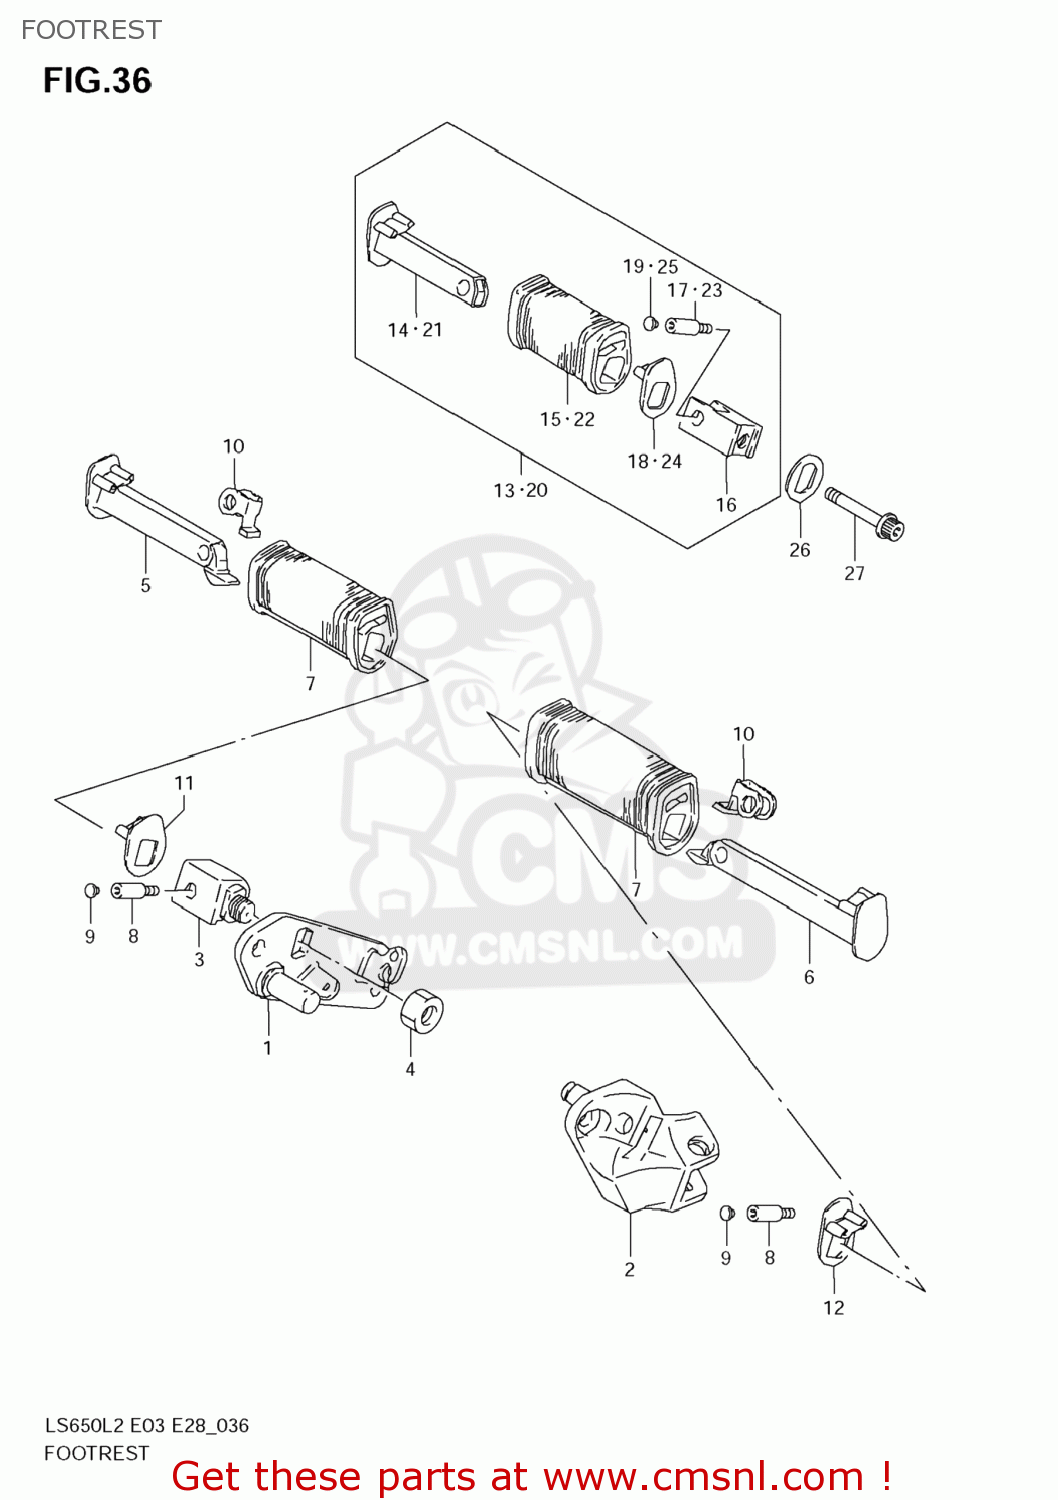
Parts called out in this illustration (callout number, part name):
1	BRACKET,FR FOOTREST,R
2	BRACKET,FR FOOTREST,L
3	HOLDER,FR FOOTREST,R
4	NUT
5	BAR,FR FOOTREST,R
6	BAR,FR FOOTREST,L
7	RUBBER,FR FOOTREST
8	BOLT(6X8)
9	CAP,PILLION FOOTREST BOLT
10	CUSHION,FR FOOTREST
11	WASHER,FR FOOTREST,R
12	WASHER,FR FOOTREST,L
13	FOOTREST ASSY,PILLION,R
14	BAR,PILLION FOOTREST,R
15	RUBBER,PILLION FOOTREST
16	HOLDER,PILLION FOOTREST
17	BOLT(6X8)
18	WASHER,FR FOOTREST,R
19	CAP,PILLION FOOTREST BOLT
20	FOOTREST ASSY,PILLION,L
21	BAR,PILLION FOOTREST,L
22	RUBBER,PILLION FOOTREST
23	BOLT(6X8)
24	WASHER,FR FOOTREST,L
25	CAP,PILLION FOOTREST BOLT
26	WASHER,PILLION FOOTREST HOLDER
27	BOLT(10X45)
